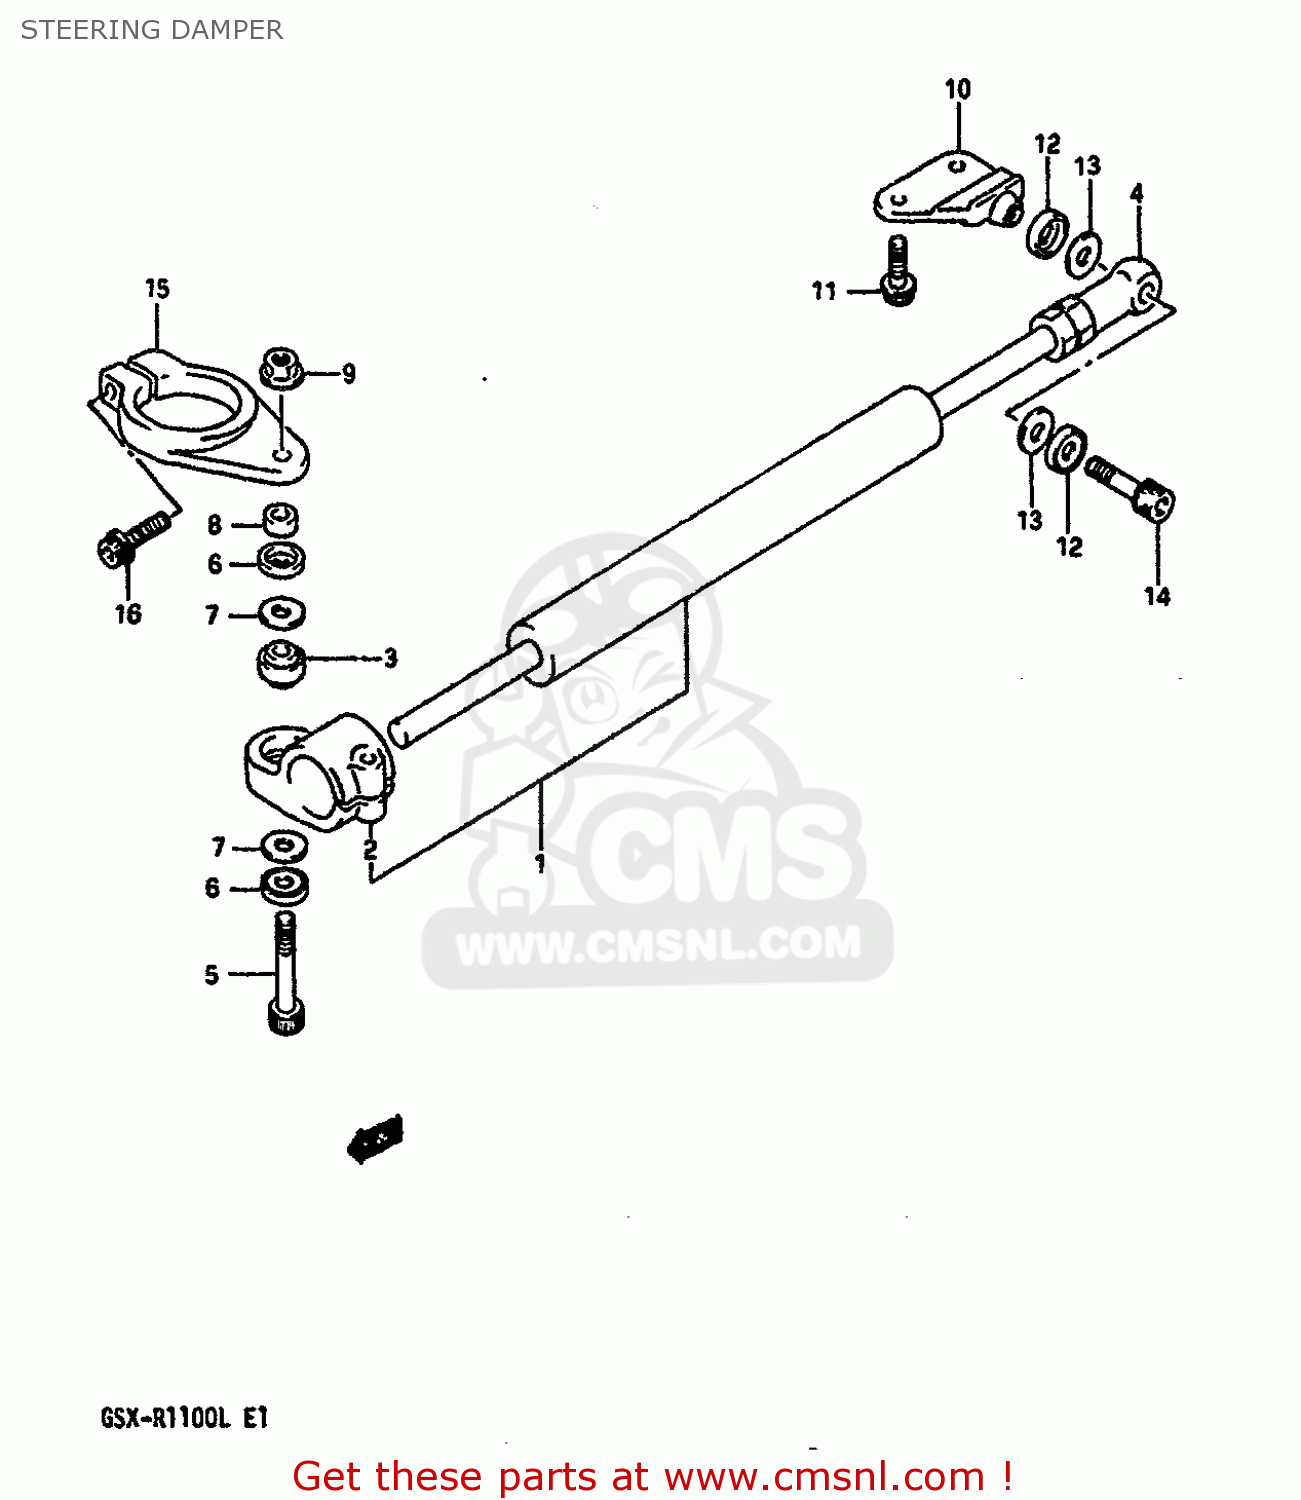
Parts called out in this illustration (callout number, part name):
1	DAMPER ASSEMBLY,STEERING
2	BRACKET,STEERING DAMPER
3	BEARING(8X18X11)
4	PILLOW BALL,ROD END
5	BOLT
6	7
7	SHIM
8	SPACER (8.4X14X6)
9	NUT
10	BOSS,STEERING DAMPER
11	BOLT
12	13
13	SHIM
14	BOLT, FRONT RH
15	BRACKET,FORK
16	BOLT,BRACKET
